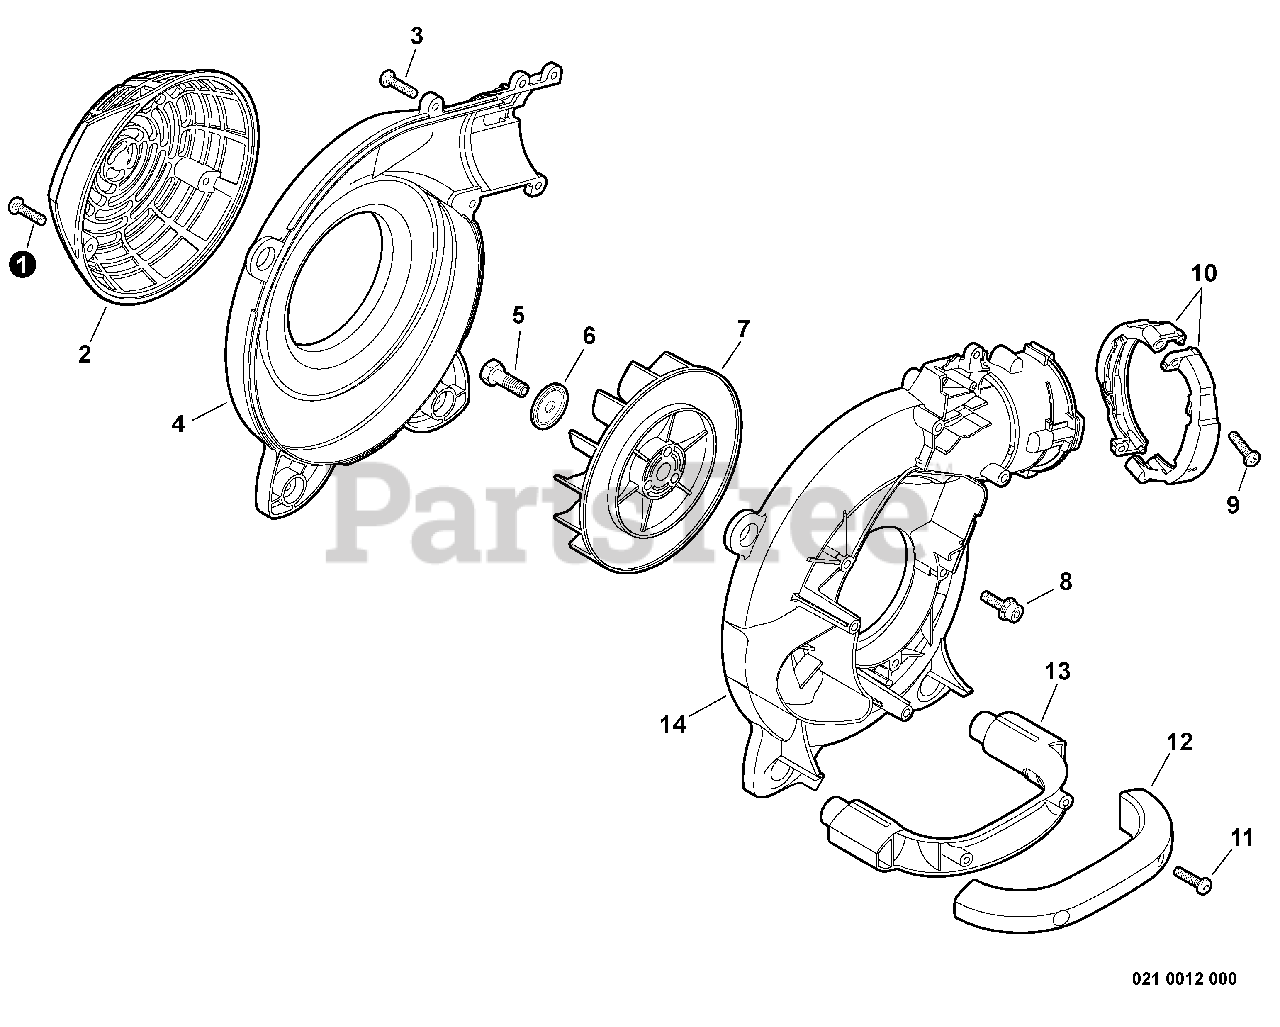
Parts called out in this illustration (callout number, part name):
1	SCREW - 5X20 -- TAPPING
2	GUARD, DEBRIS
3	SCREW - 5X20 -- TAPPING
4	COVER, FAN - LEFT
5	BOLT - 8X14
6	WASHER - CUP
8	SCREW - 4X20
9	SCREW - 5X20 -- TAPPING
11	SCREW - 5X20 -- TAPPING
12	HANDLE, LOWER - OUTER
13	HANDLE, LOWER - INNER
14	COVER, FAN - RIGHT
